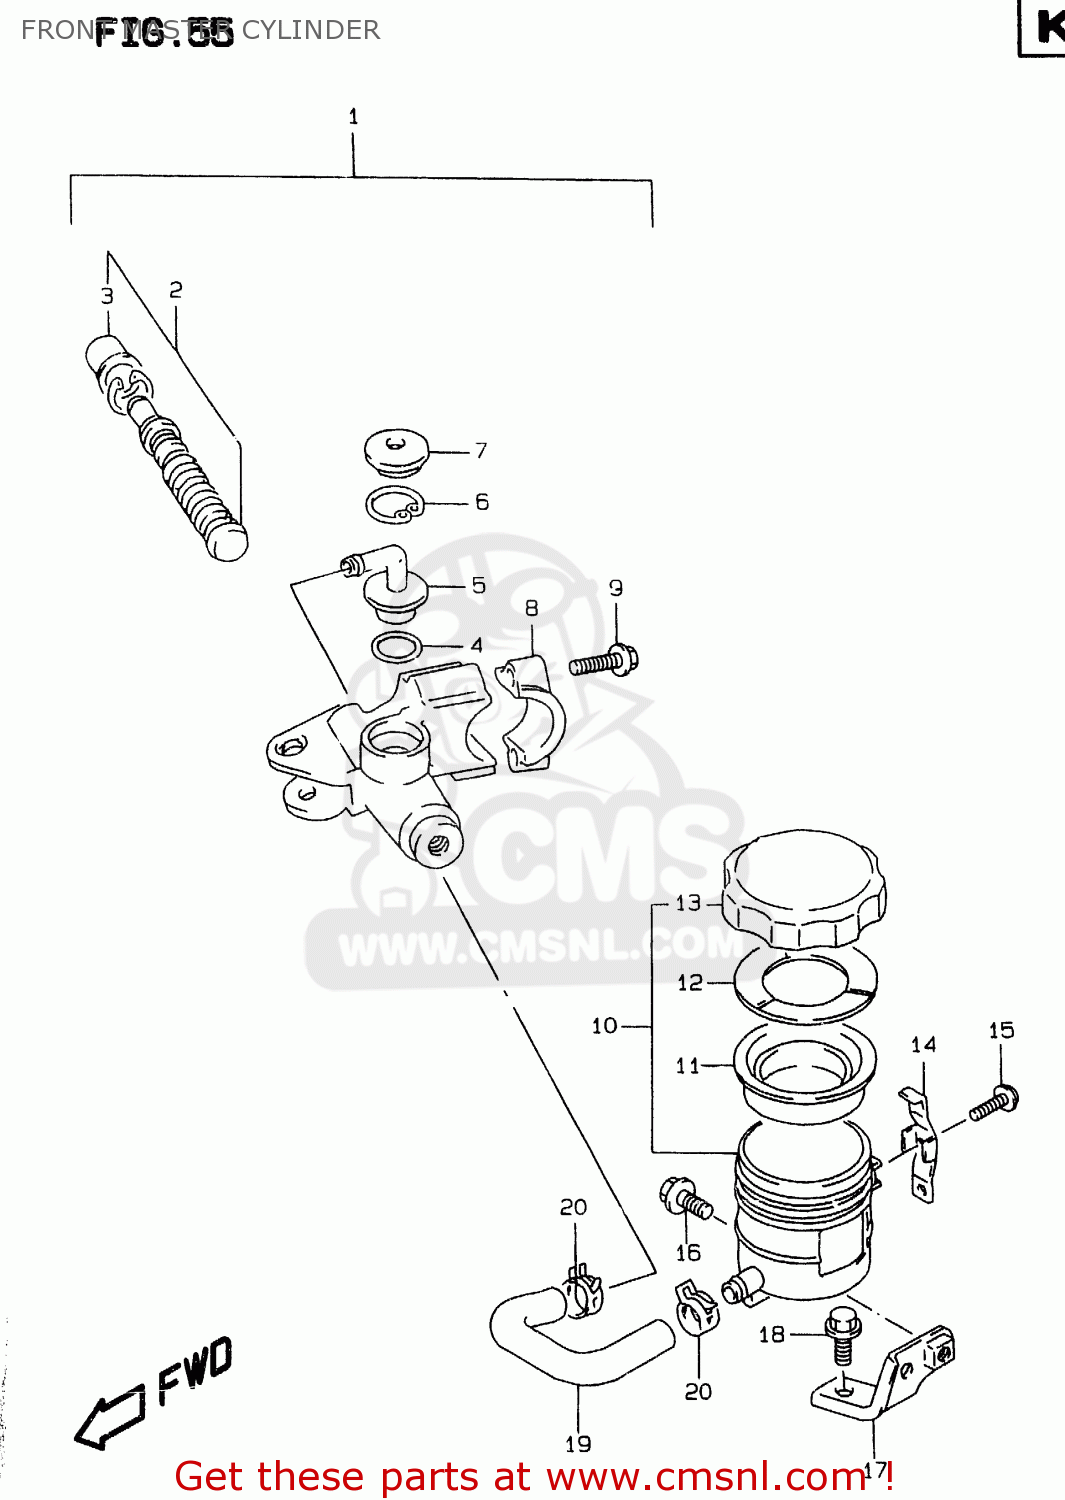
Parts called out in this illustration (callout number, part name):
1	CYLINDER ASSY,FR MASTER
2	PISTON & CUP SET
3	BOOT
4	O RING
5	CONNECTOR
6	CIRCLIP
7	COVER,DUST
8	HOLDER
9	BOLT(6X25)
10	TANK ASSY,RESERVOIR
11	DIAPHRAGM
12	PLATE,DIAPHRAGM
13	CAP
14	PLATE,RESERVOIR TANK CAP
15	SCREW
16	BOLT
17	BRACKET,RESERVOIR TANK
18	BOLT
19	HOSE,RESERVOIR TANK FR
20	CLAMP,RESERVOIR TANK FR
